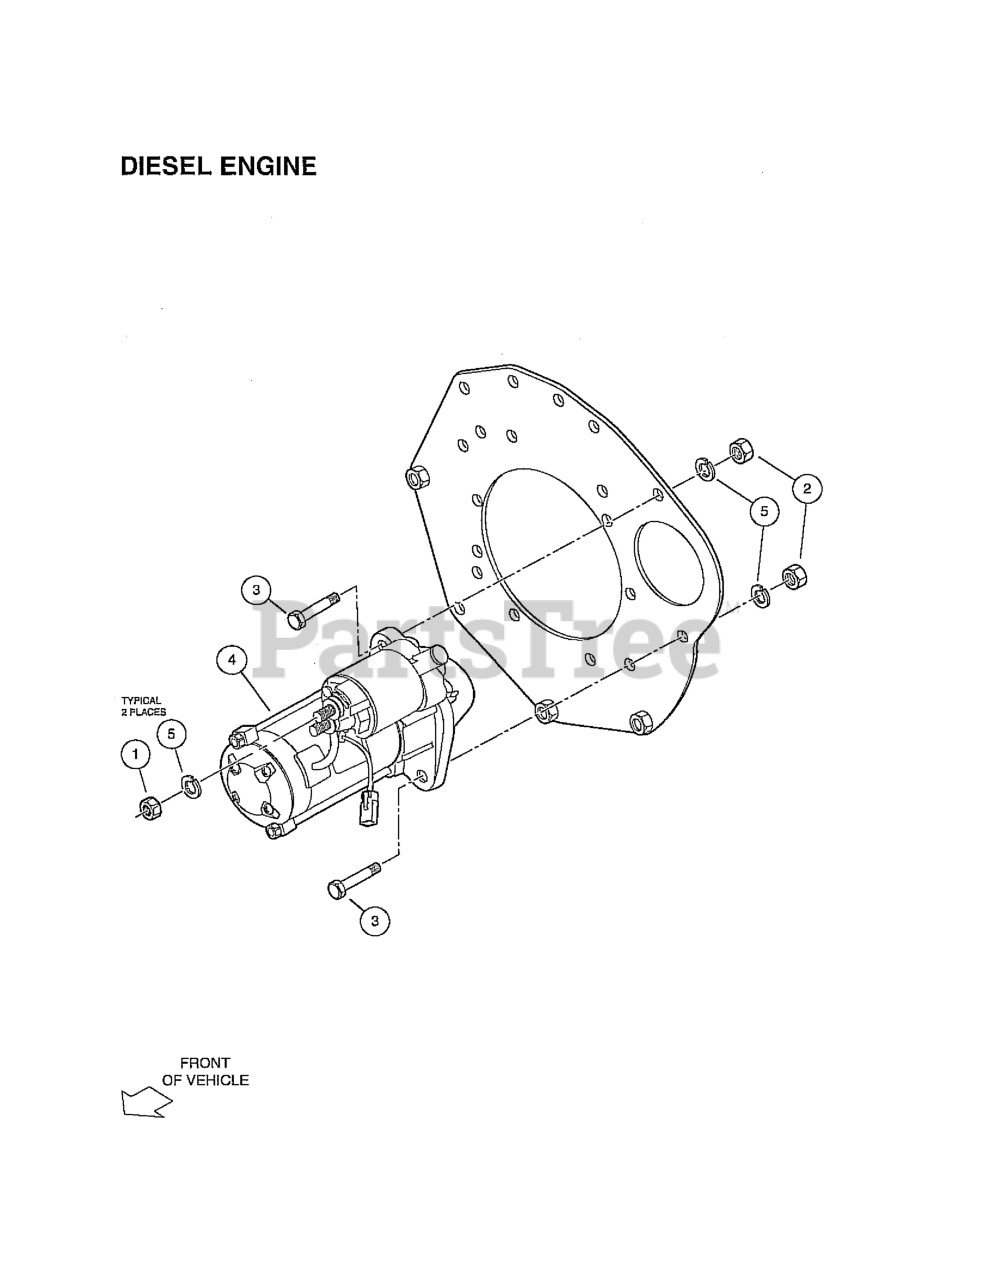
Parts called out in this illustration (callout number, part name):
1	2UT, D722 STARTER
2	NUT, M8 PLATE
3	BOLT, M8 X 1.25 X 28
4	ASSY, STARTER WAS 102648501
5	WASHER, SPRING, D722, STARTER
